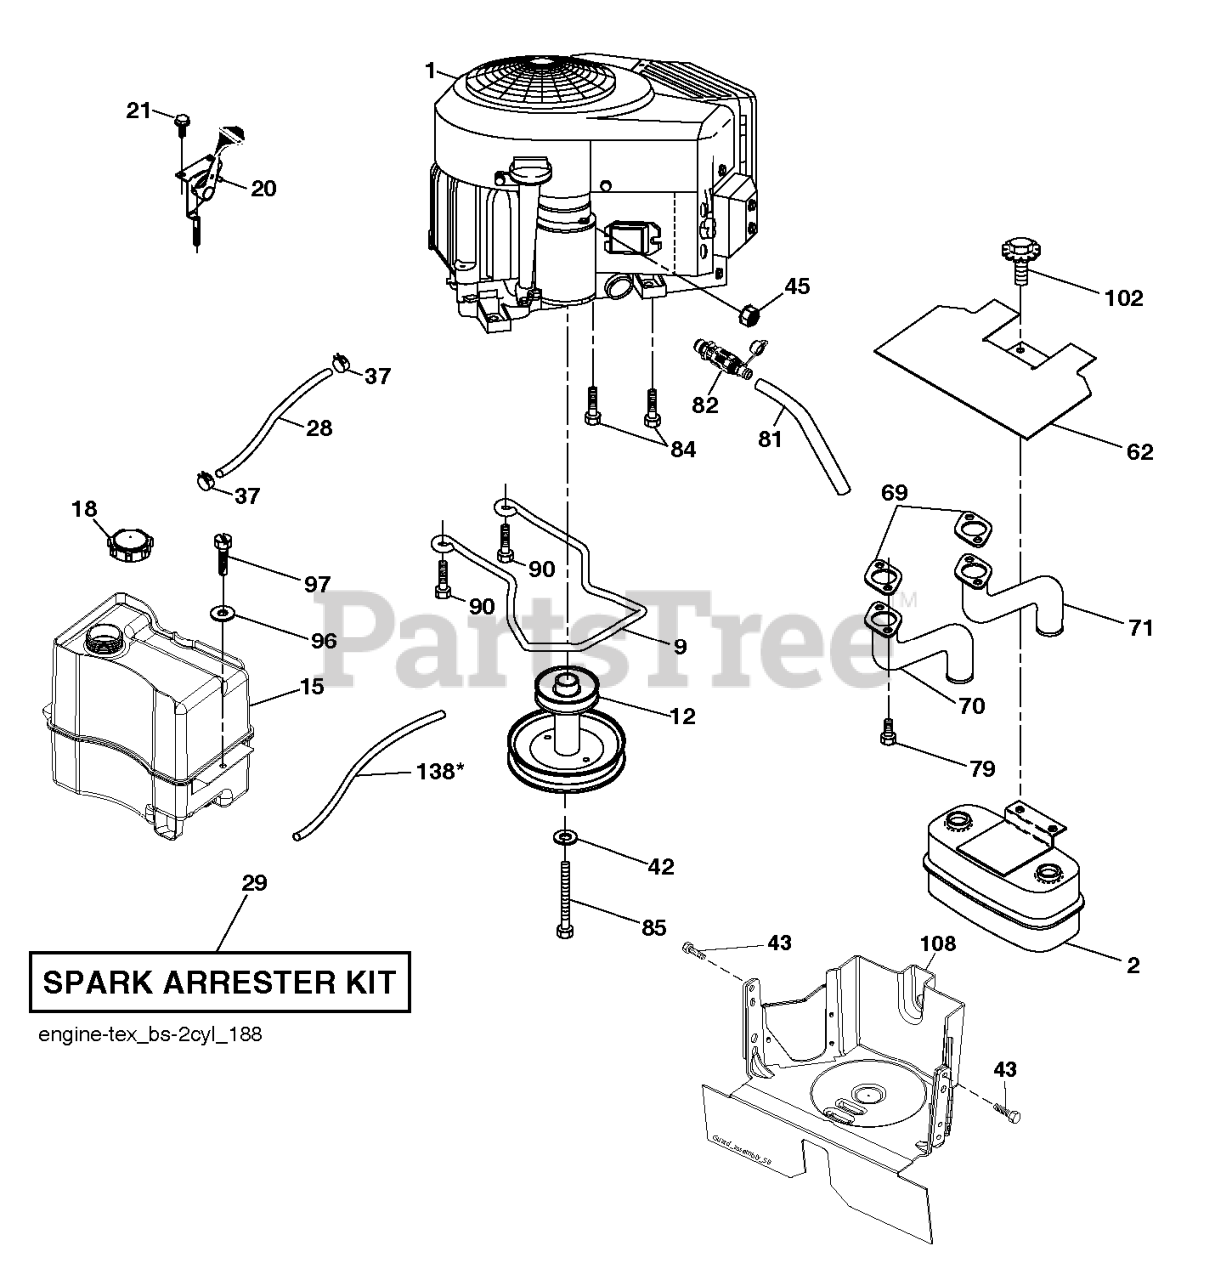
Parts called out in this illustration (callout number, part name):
2	MUFFLER.ASM.TWIN.MNTG.BRACKET
12	ENGINE.PULLEY
15	FUEL TANKS
15	TANK.ASSEMBL.2.5GAL.NON-EPA
18	CAP ASM.FUEL.2.25"FR.
20	THROTTLE CABLE
28	LINE.FUEL.20
29	KIT.SPARK ARRESTOR 794945 B&S
37	HOSE CLAMP
62	SHIELD.HEAT.MUFFLER
69	GASKET.MUFFLER
70	EXHAUST.TUBE.LH.BS/TWIN
71	EXHAUST.TUBE.RH.B&S.TWIN.INTEK
81	TUBE, DRAIN OIL ASM.
82	VALUE.OIL.DRAIN
84	SCREW.3/8-16
85	BOLT.HEX.7/16-20X4.GR5.1.5BLUE
90	SCREW 3/8-16X1
97	SCREW HEXWSHR 1/4-20X3/4
102	SCREW
108	COVER ENGINE PULLEY COVER WITH
